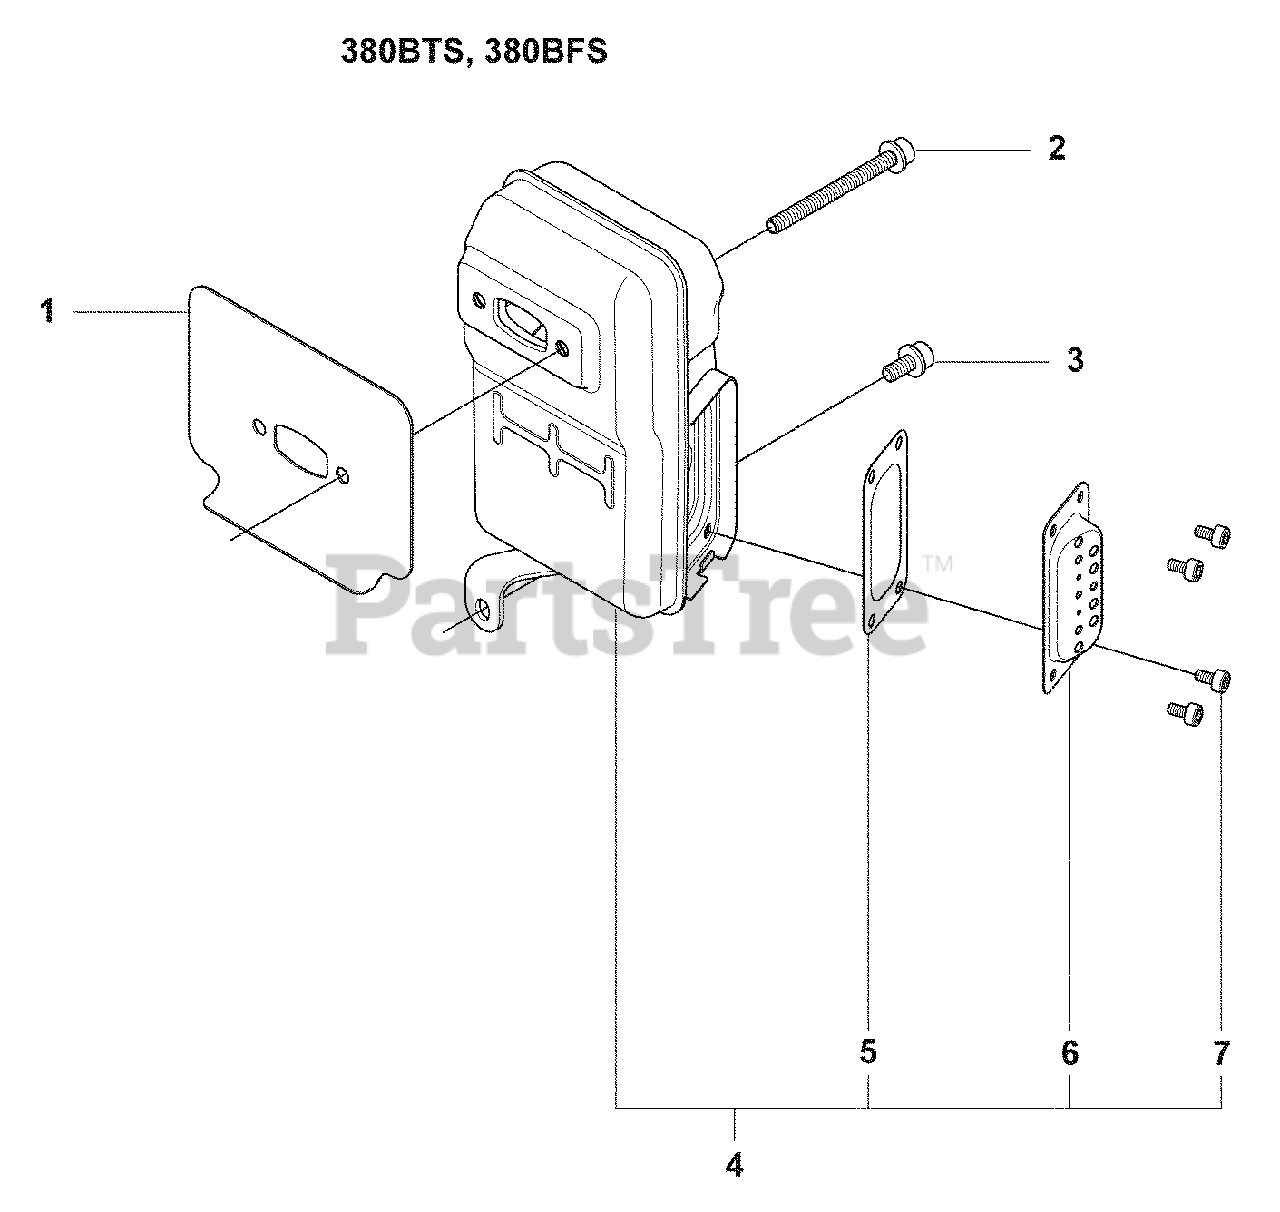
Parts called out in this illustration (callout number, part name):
3	Bolt
4	Muffler Assembly
6	RP_DIFFUSER
